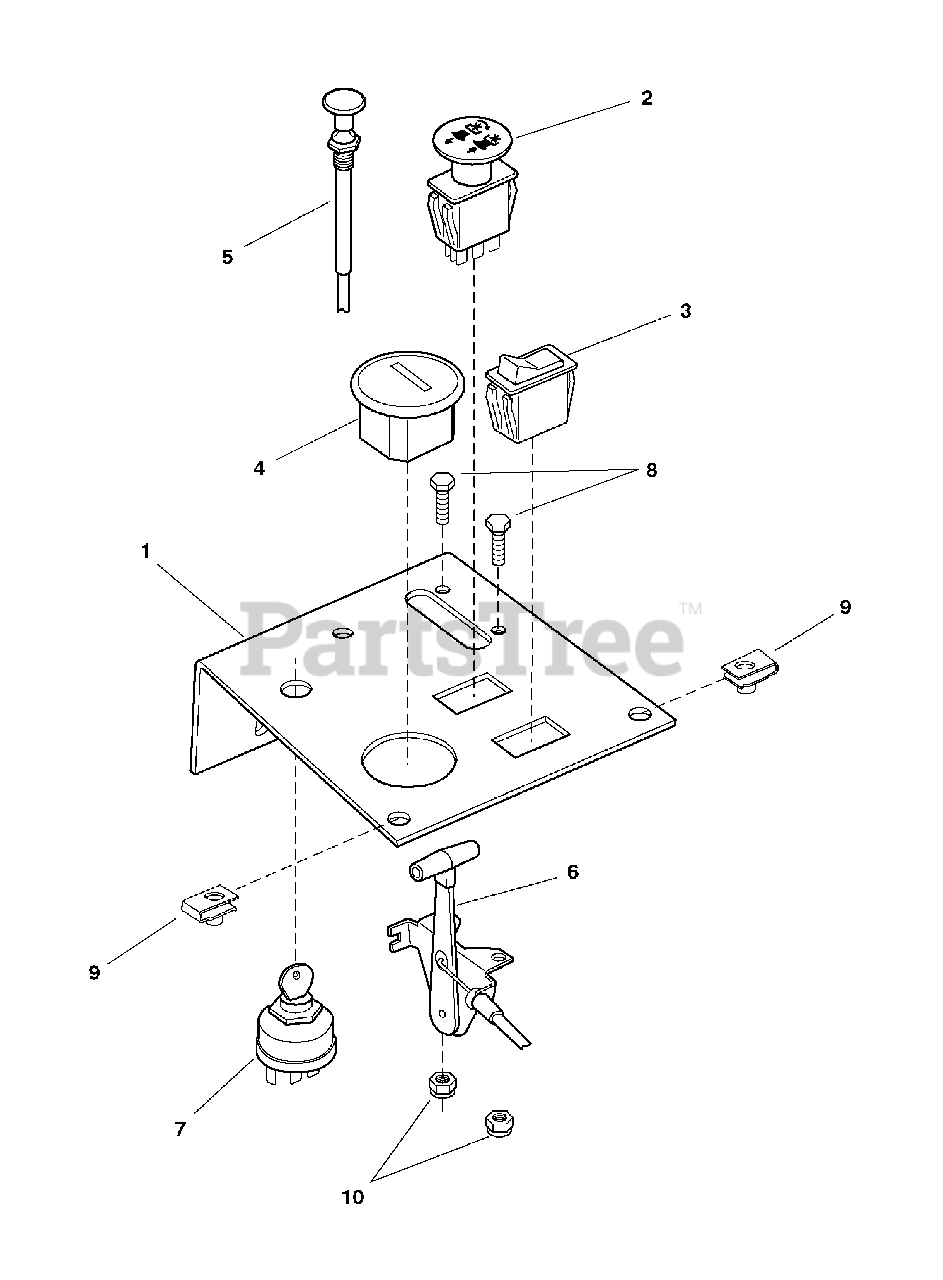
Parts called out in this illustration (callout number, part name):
1	INSTRUMENT PANEL
2	SWITCH, PTO
3	SWITCH, Headlight
5	CABLE, Choke
6	CABLE, Throttle
7	SWITCH, Ignition
8	CAPSCREW, Hex Hd, 1/4-20 x 3/4
9	BODY CLIP, 5/16-18
10	NUT, Hex, Nylon Lock, 1/4-20
